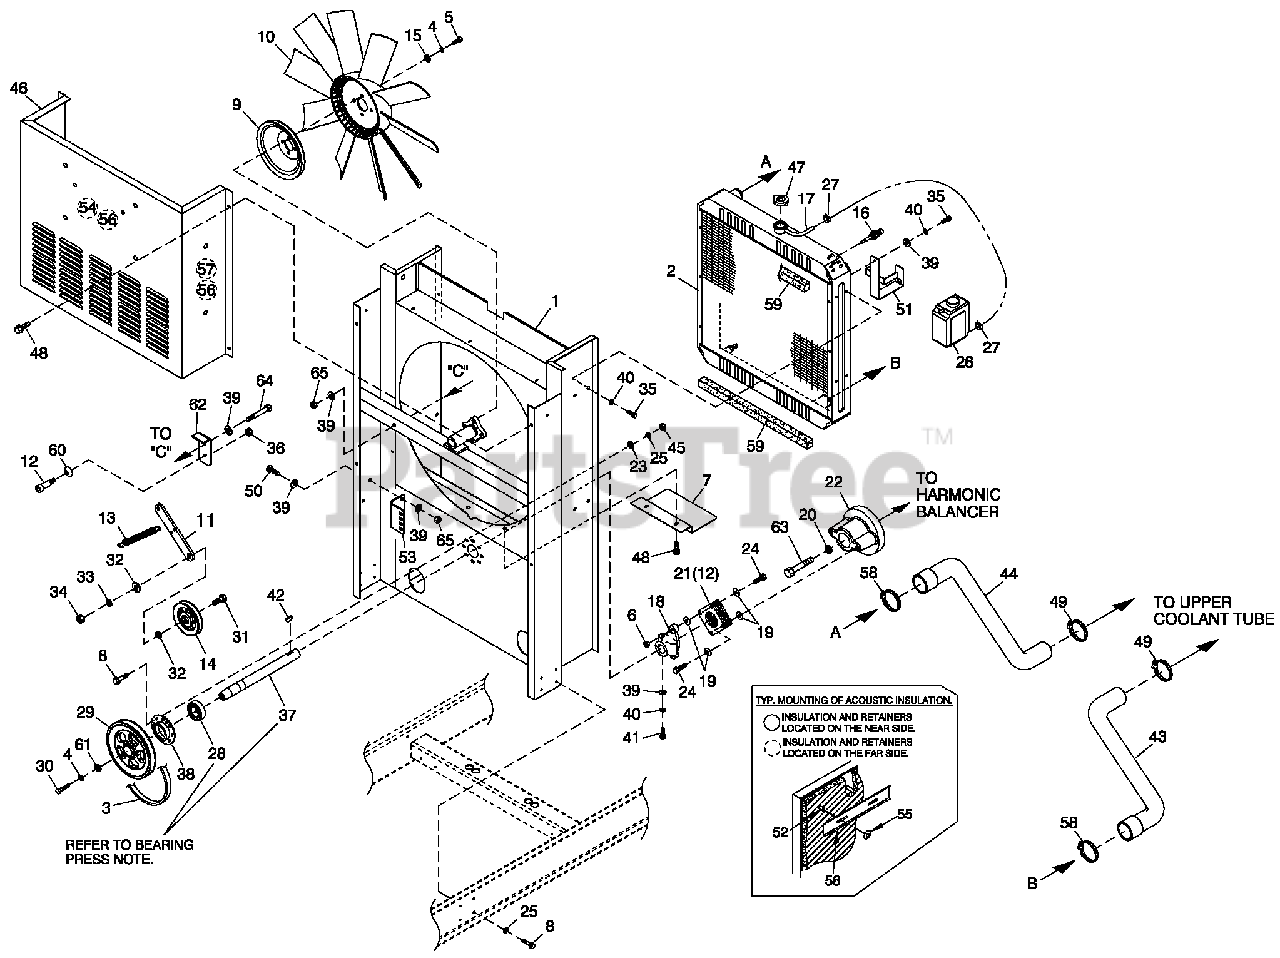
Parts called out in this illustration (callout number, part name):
1	WELDMENT RADIATOR SUPPORT C4
2	RADIATOR 598 X 568 X 49 CPL LH
3	V- BELT 31/64" X 57-3/8"
4	WASHER LOCK M10
5	SCREW HHC M10-1.5X30G10.9
6	NUT HEX LOCK 5/16-24 NY INS
7	SHIELD RADIATOR C4
8	SCREW HHFC M6-1.0X20G8.8
9	PULLEY FAN V-GROOVE 9"
10	FAN COOL 22" DIA 10 BLADE LH
11	FLATTENSIONERARM
12	SHOULDER BOLT 3/8 X 1/2"
13	SPRING TENSION CPL
14	PULLEY V- BELT 4" FLANGED
15	WASHER FLAT 3/8-M10 ZINC
16	PRO BE COOLANT LEVEL 3/8 NPTF
17	HOSE 9/32 ID (27"LG)
18	HU B FLEX PLATE
19	WASHER FLEX (THIN)
20	WASHER LOCK M12
21	DISK FLEX
22	COUPLING FLEX HU B MACHINED G3
23	WASHER FLAT 1/4-M6 ZINC
24	SCREW HHC 5/16-24X1.124
25	WASHER LOCK M6-1/4
26	TANK COOLANT RECOVERY
27	CLAMP HOSE BAND 1/4
28	BEARING #6205 2NSE C3 E SRI2 S
29	PULLEY 5.5" DIA MACHINED
30	SCREW HHCM10-1.5X30 G8.8
31	SCREW HHC 1/2-13 X 2" G8
32	WASHER FLAT 1/2 ZINC
33	WASHER LOCK 1/2
34	NUT HEX 1/2-13 STEEL
35	SCREW HHFC M8-1.25 X 20 W/M6
36	NUT HEX LOCK 5/16-18 NY INS SS
37	SHAFT FAN DRIVE C4 3 .0LG14
38	RETAINER BEARING
39	WASHER FLAT 5/16-M8 ZINC
40	WASHER LOCK M8-5/16
41	SCREW HHC M8-1.2 5X 3 5 G8.8
42	KEY WOODRUFF 4X 1 9D
43	HOSE, RADIATOR UPPER FRONT
44	HOSE, RADIATOR LOWER FRONT
45	NUT HEX M6X 1.0 G8YEL CHR
46	INNER DISCHARGE DUCT, C4
47	CAP RADIATOR 13 PSI
48	SCREW THF M6-1 X 16 N WA Z/JS
49	CLAMP HOSE #24 B1.06-2.00
50	SCREW HHC M8-1.2 5X 2 0 C8.8
51	BRACKET COOLANT TANK
52	INSULATION RETAINMENT HANGER
53	BRACKET TENSIONER SPRING
54	INSULATION FRONT INNER DUCT
55	WASHER SELF LOCKING DOME
56	RETAINER INSULATION (450)
57	INSULATION INNER DUCT
58	CLAMP HOSE #28 1.32-2.25
59	TAPE FOAM 1 X 1 (26.75" LG)
60	WASHER BELLEVILLE .75X.38X.028
61	SPACER .5 X 1.5 X .25 STL/ZINC
62	TENSIONER ARM SUPPORT BENT 90
63	SCREW HHCM12-1.5X75 C8.8
64	SCREW HHC M8-1.2 5X 7 5 C8.8
65	NUT HEX LOCK M8-1.25 NY INS
